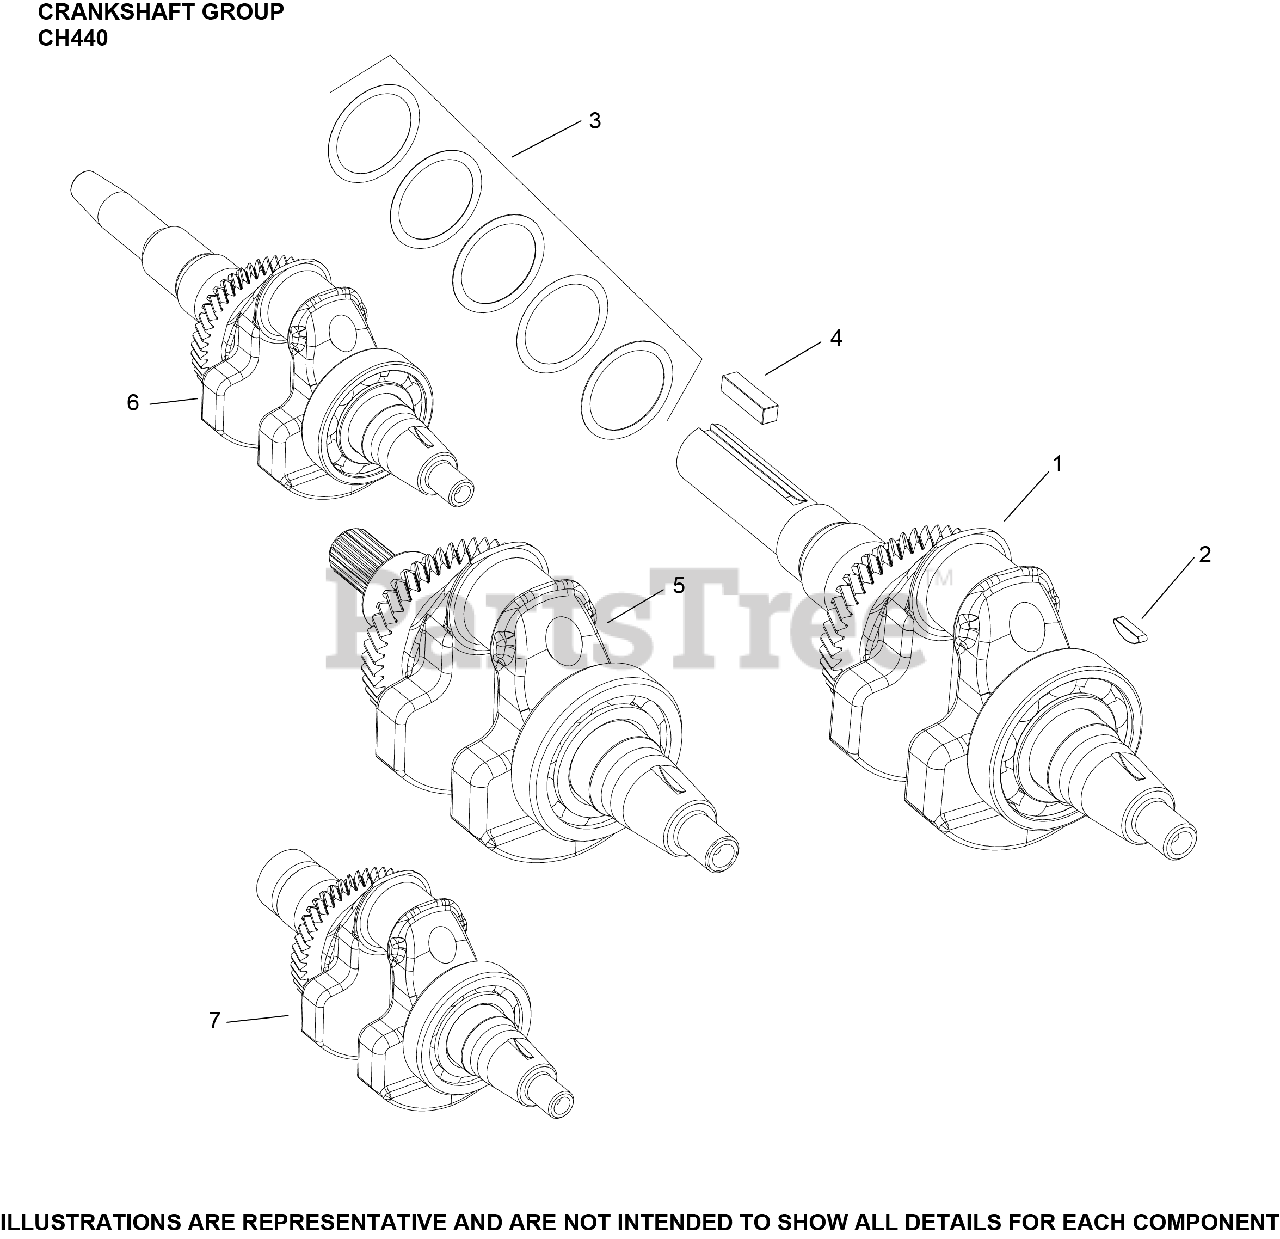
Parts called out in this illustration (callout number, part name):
1	CRANKSHAFT ASSEMBLY
2	KEY, FLYWHEEL
3	KIT, SHIM
